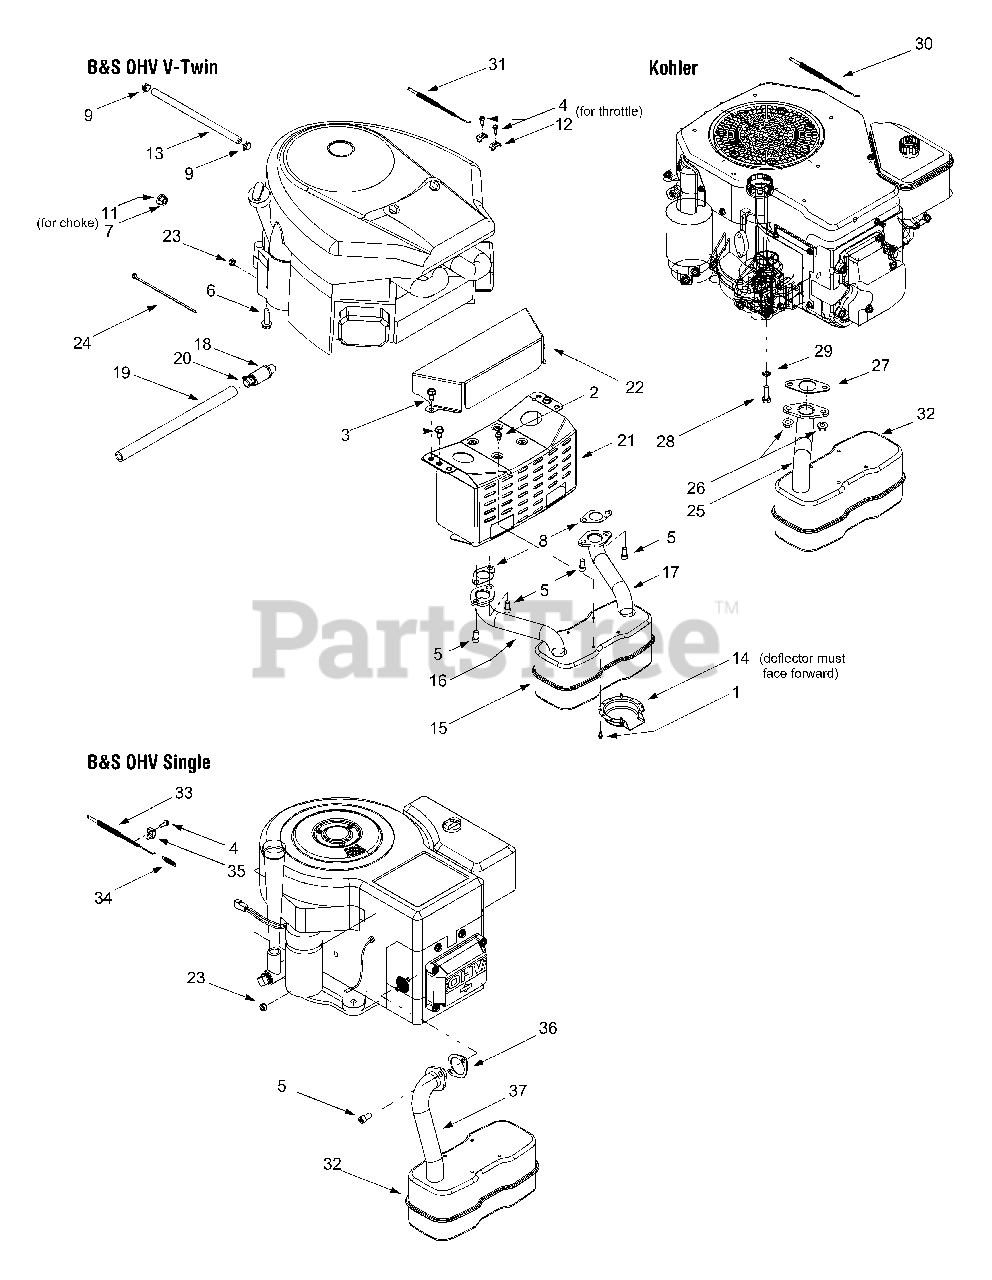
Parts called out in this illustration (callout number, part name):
1	Self-tapping Screw, #8-18 x.50
2	Self-tapping Screw, 1/4-20 x.50
3	Self-tapping Screw, 5/16-18 x.625
4	Screw, #10-32 x.625 (B&S OHV V-Twin)
5	Socket Cap Screw, 5/16-18 x.625
6	Self-tapping Screw, 3/8-16 x 1.25
7	Hex Nut, 3/8-16
8	Exhaust Gasket (B&S OHV V-Twin)
10	Casing Clamp (B&S OHV Single)
11	Lock Washer,.406 x.875 x.059
12	Casing Clamp (B&S OHV V-Twin)
13	Fuel Line Hose
14	Muffler Deflector
15	Muffler, Twin Inlet (B&S OHV V-Twin)
16	RH Exhaust Pipe (B&S OHV V-Twin)
17	LH Exhaust Pipe (B&S OHV V-Twin)
18	Oil Drain Valve
19	Oil Drain Hose
20	Oil Drain Cap
22	Engine Heat Shield (B&S OHV V-Twin)
23	Hex Sems Nut, 1/4-20 (B&S OHV V-Twin)
25	Exhaust Pipe (Kohler)
26	Flange Nut, 8mm (Kohler)
27	Exhaust Gasket (Kohler)
28	Hex Cap Screw, 8mm (Kohler)
29	External Lock Washer (Kohler)
30	Throttle Cable (Kohler)
31	Throttle Cable (B&S OHV V-Twin)
32	Muffler, Single Inlet (Kohler)
33	Throttle Cable (B&S OHV Single)
34	Extension Spring, .275 x 1.25 (B&S OHV Single)
35	Casing Clamp (B&S OHV Single)
36	Exhaust Gasket (B&S OHV Single)
37	Exhaust Pipe (B&S OHV Single)
